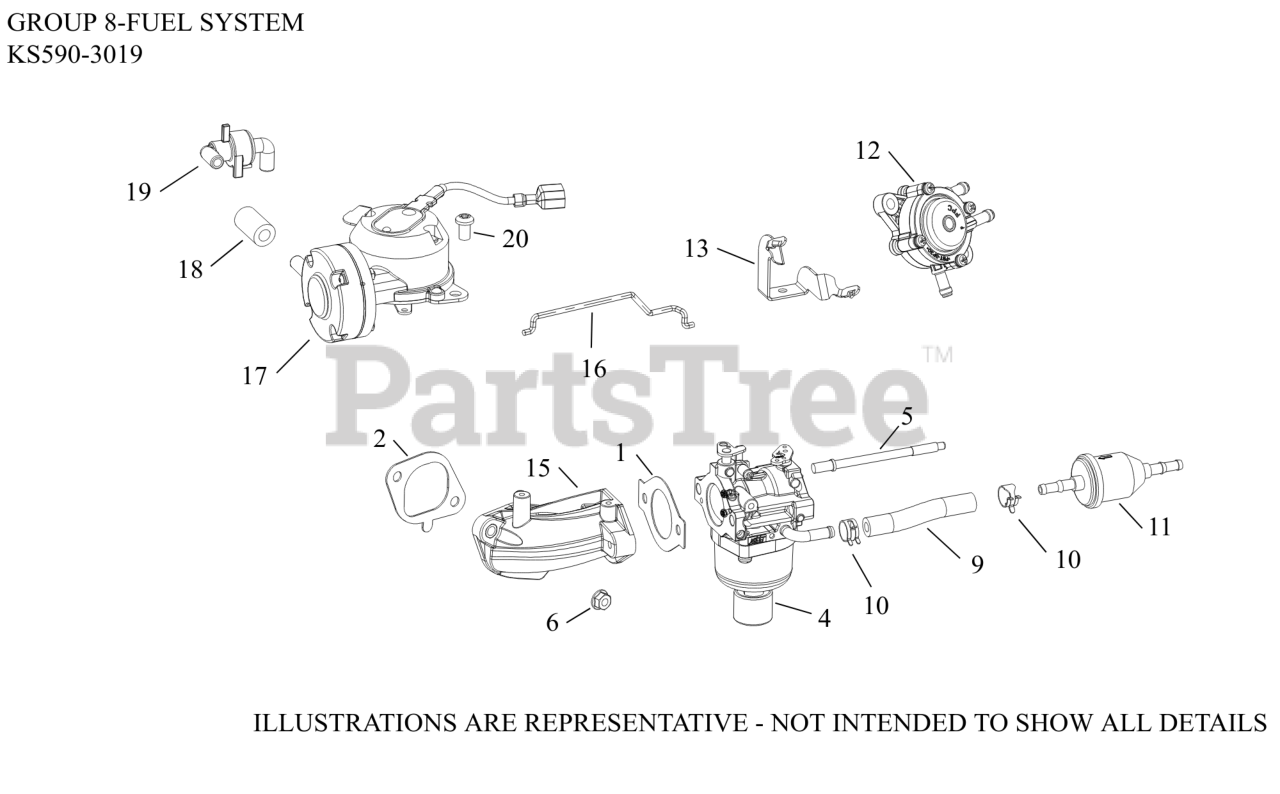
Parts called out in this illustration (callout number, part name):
1	GASKET, CARBURETOR (THROTTLE)
2	GASKET, INTAKE MANIFOLD
4	KIT,CARB(NIKKI)
5	STUD, CARBURETOR
6	NUT, FLG M6X1.0
9	HOSE,LW PERM.FUEL 24.00"-USE 25 111 81-S
10	SPRING CLAMP, HOSE
11	FILTER,FUEL 51 MICRON (FUEL PUMP)
12	PUMP, FUEL (PULSE)-(#2539326S)
13	BRACKET, FUEL PUMP
15	MANIFOLD, INTAKE ASSY
16	LINKAGE, CHOKE
17	DIAPHRAGM ASSY
18	HOSE, VACUUM
19	CHECK VALVE ASSY
20	SCREW, K40 X 1.79 TFS
NI	HIGH ALTITUDE KIT (5000 FT)
NI	KIT, OVERHAUL
NI	KIT, CHOKE SHAFT
NI	KIT, O-RING
NI	KIT, SOLENOID (NIKKI)
NI	KIT, BOWL WITH O-RINGS
NI	KIT, FLOAT & INLET NEEDLE FOR FUEL PUMP
NI	KIT, THROTTLE SHAFT
